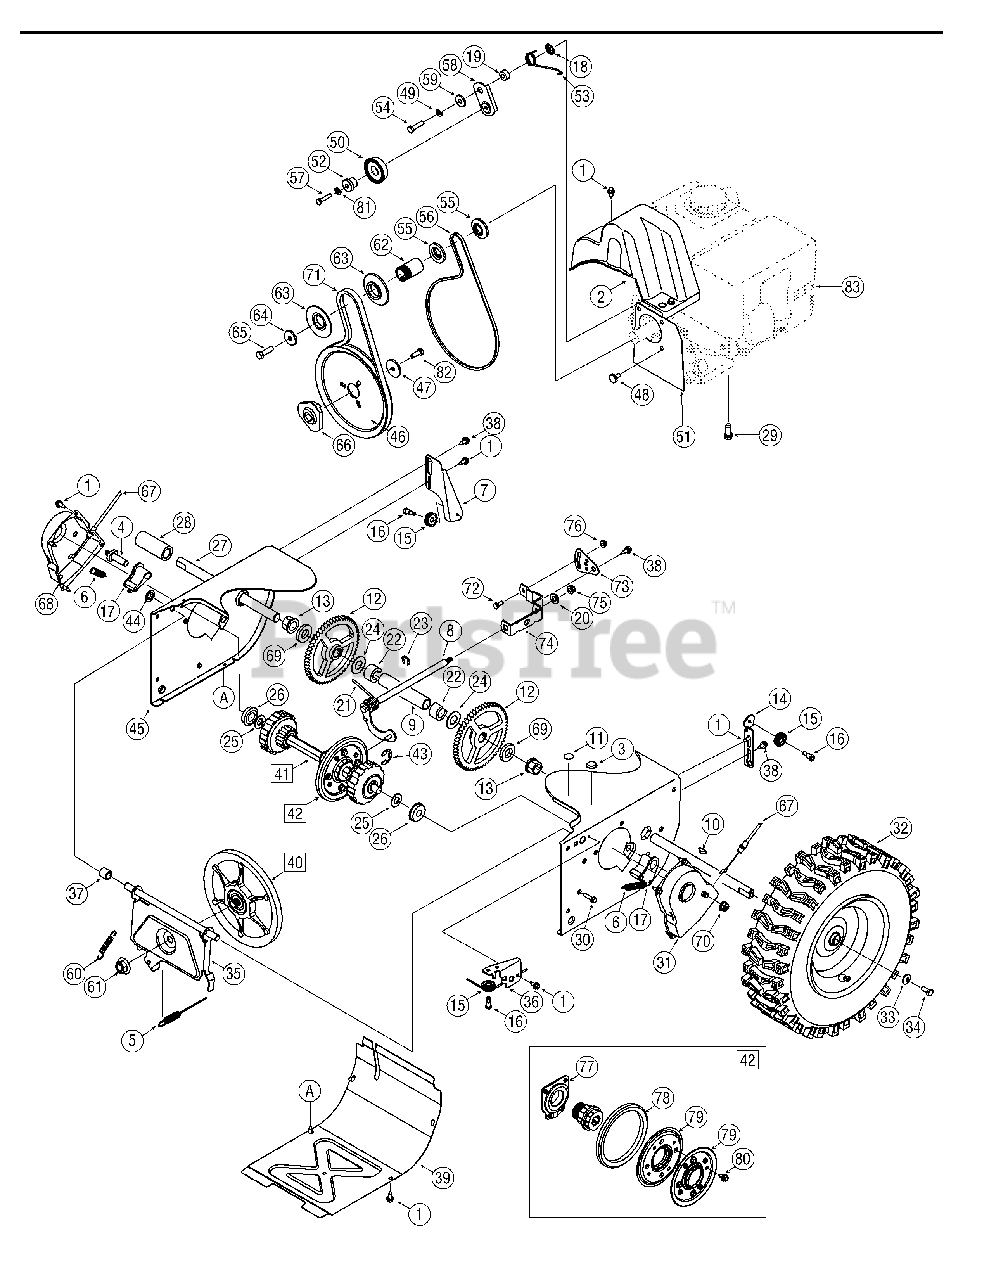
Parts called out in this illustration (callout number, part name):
1	AB Screw, 1/4-20 x 0.625
2	Belt Cover
3	Plug, 3/8 ID
4	Actuator Shaft
5	Drive Clutch Cable
6	Extension Spring
7	Drive Clutch Cable Guide Bracket
8	Shift Rod Assembly
9	Axle Support Tube
10	Hi Pro Key
11	Plug, 1/2 ID
12	Gear, 56T
13	Hex Flange Bearing
14	Auger Clutch Cable Guide Bracket
15	Cable Roller
16	C Screw, 1/4-28 x 0.375
17	Dogg Assembly - LH
17	Dogg Assembly - RH
18	Push-on Nut
20	Washer, Flat
21	Torsion Spring, .750 ID x .968 Lg.
22	Spacer
23	E Ring
24	Flat Washer, .76 x 1.49 x .06
25	Flat Washer
26	Ball Bearing
28	Spacer
29	TT Sems Screw, 3/8-16 x 1.0
30	TT Screw, 1/4-20 x 1.0
31	Shaft Retainer - LH
32	Wheel Complete - LH
32	Wheel Complete - RH
33	Bell Washer
34	Hex Bolt, 5/16-24 x 0.75
35	Friction Wheel Support Brkt. Assy.
36	Auger Cable Guide Bracket
37	Spacer
38	Shoulder Screw
39	Frame Cover
40	Friction Wheel Disc Assembly
41	Drive Shaft Assembly
42	Friction Wheel Assembly
43	Retainer Ring
44	Speed Nut
45	Wheel Drive Frame
46	Auger Pulley
47	Flat Washer
48	Shoulder Screw
49	Lock Washer
50	Idler Pulley Assembly
51	Cover Plate
52	Spacer
53	Torsion Spring
54	Hex Screw, 5/16-24 x 1.25
55	Pulley Half
56	Belt, Wheel Drive
57	TT Screw, 1/4-20 x 1.25
58	Drive Clutch Idler Bracket
59	Shoulder Spacer
60	Extension Spring
61	Flange Nut, 5/8-18
62	Spacer
63	Pulley Half
64	Flat Washer
65	Hex Bolt, 3/8-24 x 1.25
66	Pulley Adapter
67	Steering Cable
68	Shaft Retainer - RH
69	Axle Spacer
70	Flange Lock Nut, 3/8-16
71	V-Belt,.500 x 35.00 Lg
72	Hex Screw, 1/4-20 x .620
73	Speed Selector Pivot Bracket
74	Speed Selector Shift Bracket
75	Flange Lock Nut, 5/16-18
76	Flange Lock Nut, 1/4-20
77	Friction Wheel Bearing Assembly
78	Friction Wheel
79	Friction Plate
80	Screw, 1/4-20 x .500
81	Lock Washer
82	Hex Bolt, 5/16-24 x 0.875
83	Replacement Engine
